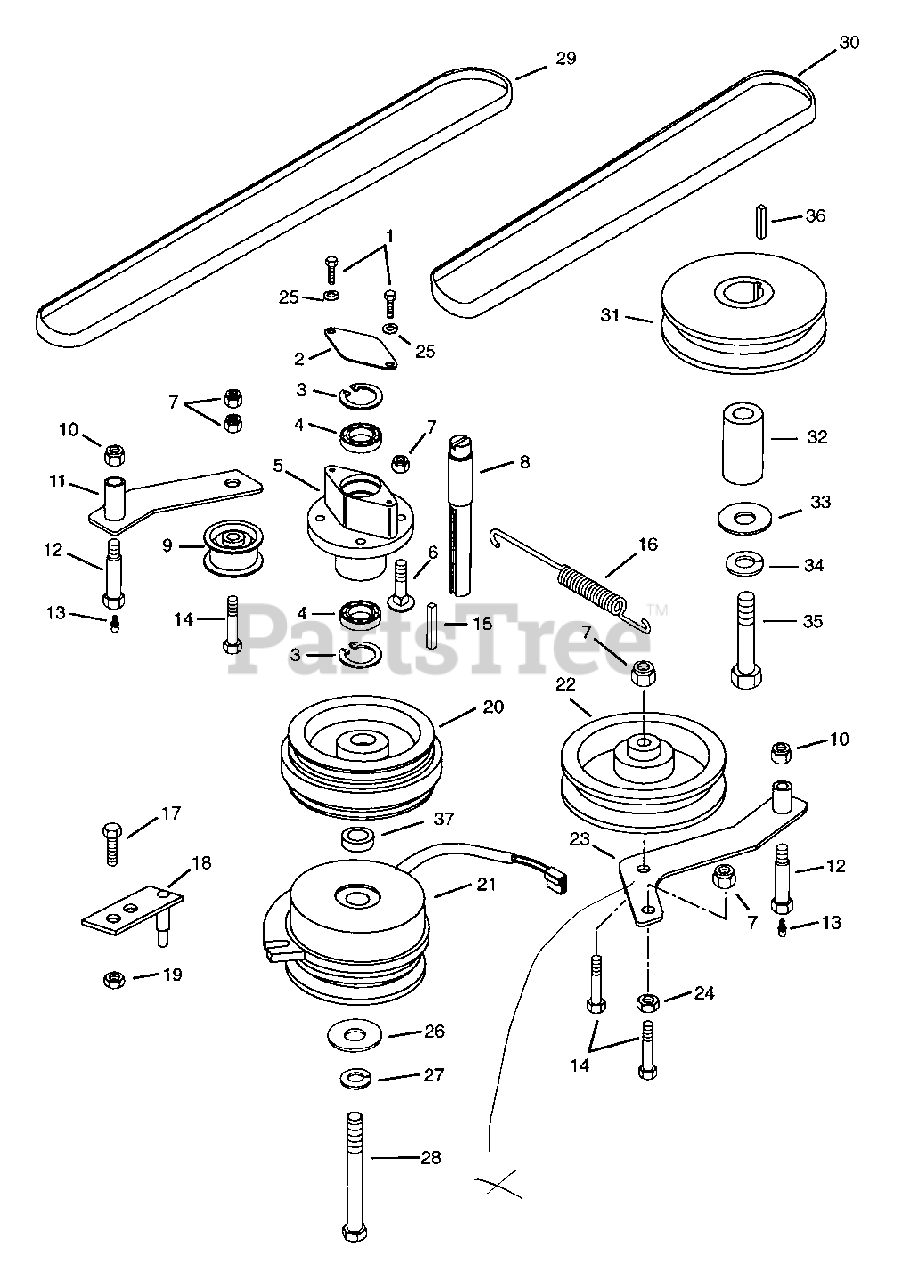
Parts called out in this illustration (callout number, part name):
1	Bolt-Hex .38-16 x .50 Grade 5
2	Plate, Cover
3	Ring-Retaining-Internal 2.210 x .082
4	Bearing-Ball 1.0 x 2.0 x .56
6	Bolt-Round Head Square Neck .38-16 x 1.50 Grade 5
7	Nut-Locking-Nylon .375-16
9	Idler-Flat 2.468 x .38
10	Nut-Locking-Nylon .50-13
11	Transmission Idler
12	Shoulder Bolt, Idler Pivot
13	Fitting Lube
14	Bolt-Hex .38-16 x 2.00 Grade 5
15	Key-Square .248 x 1.25 x .248
16	Spring-Tension .113 x .812 x 7.00
17	Bot-Hex .31-18 x .75 Grade 5
18	Weldment, PTO Clutch Anchor
19	Nut-Locking-Nylon .312-18
20	Sheave, Jackshaft
21	Clutch, Electric - Warner
22	Pulley-Idler 4.50 x .380
23	Weldment, Main Idler
24	Nut Hex .375-16
25	Washer-Lock .375 x .155
26	Washer-Special .469 x 2.000 x .250
27	Washer-Lock .44 Reg.
28	Bot-Hex .44-20 x 2.25 Grade 5
29	V-Belt, Engine to Jackshaft
30	V-Belt, Jackshaft-Transmission
31	Sheave, Engine
32	Bushing, Steel 1.000 x 1.25 x 1.58
33	Washer-Flat-Steel .438 x 1.375 x .083
34	Washer-Lock .438 x .133
35	Bolt-Hex .44-20 x 1.50 Grade 5
35	Bolt-Hex Metric 10MM - 1.5 x 30MM
36	Key-Square .25 x 1.00 x .25
37	Spacer, 1.02 x 1.38 x .20
